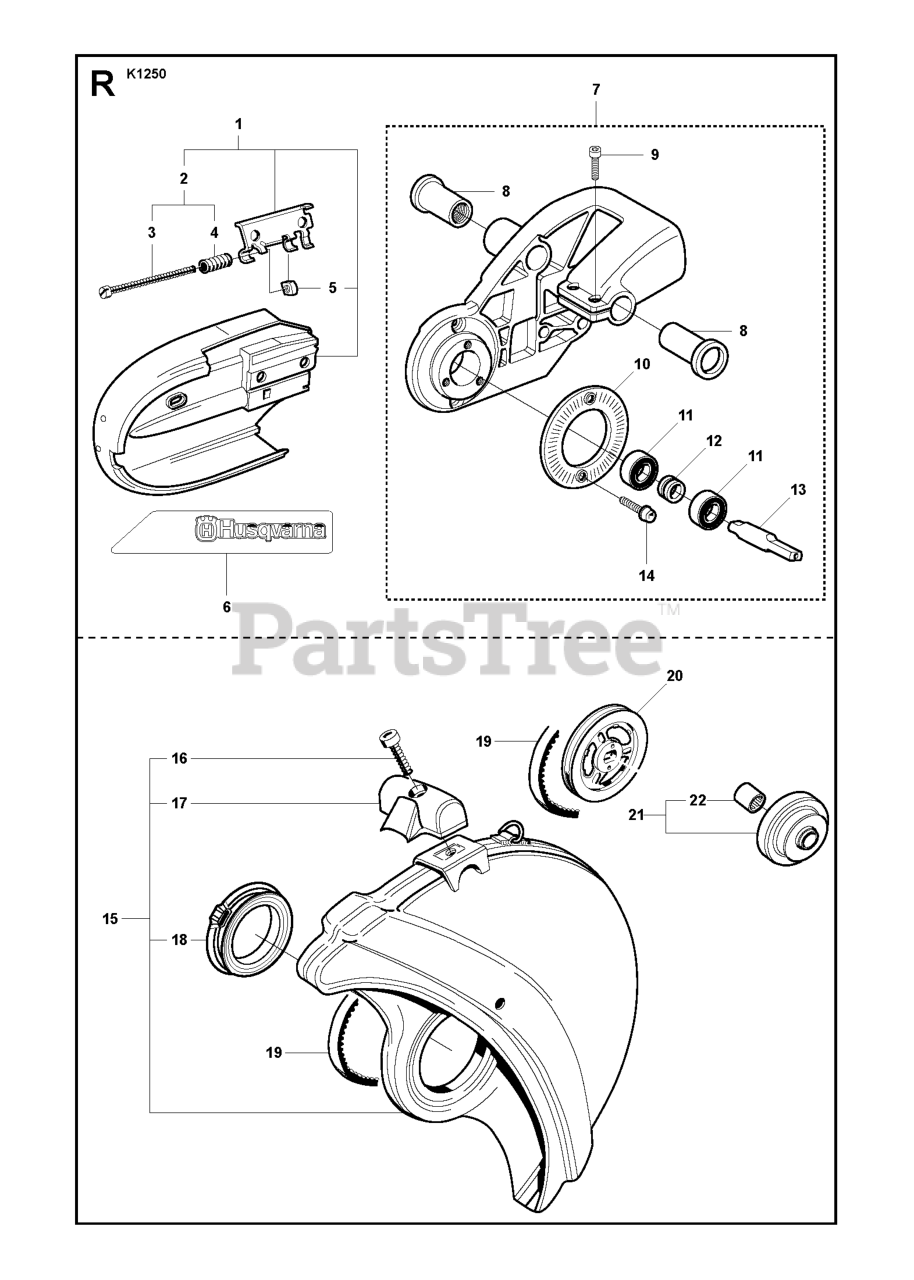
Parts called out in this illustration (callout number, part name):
1	PROTECTOR
7	RP BEARING HOUSING RAIL 16"
7	RP BEARING HOUSING
7	BEARING HOUSING
11	BALL BEARING
15	PROTECTOR
15	RP GUARD
16	SCREW MC6S 5X20
19	BELT
20	%PULLEY
21	CLUTCH DRUM 14"
21	WHEEL
22	SUPPORT BUSHING
